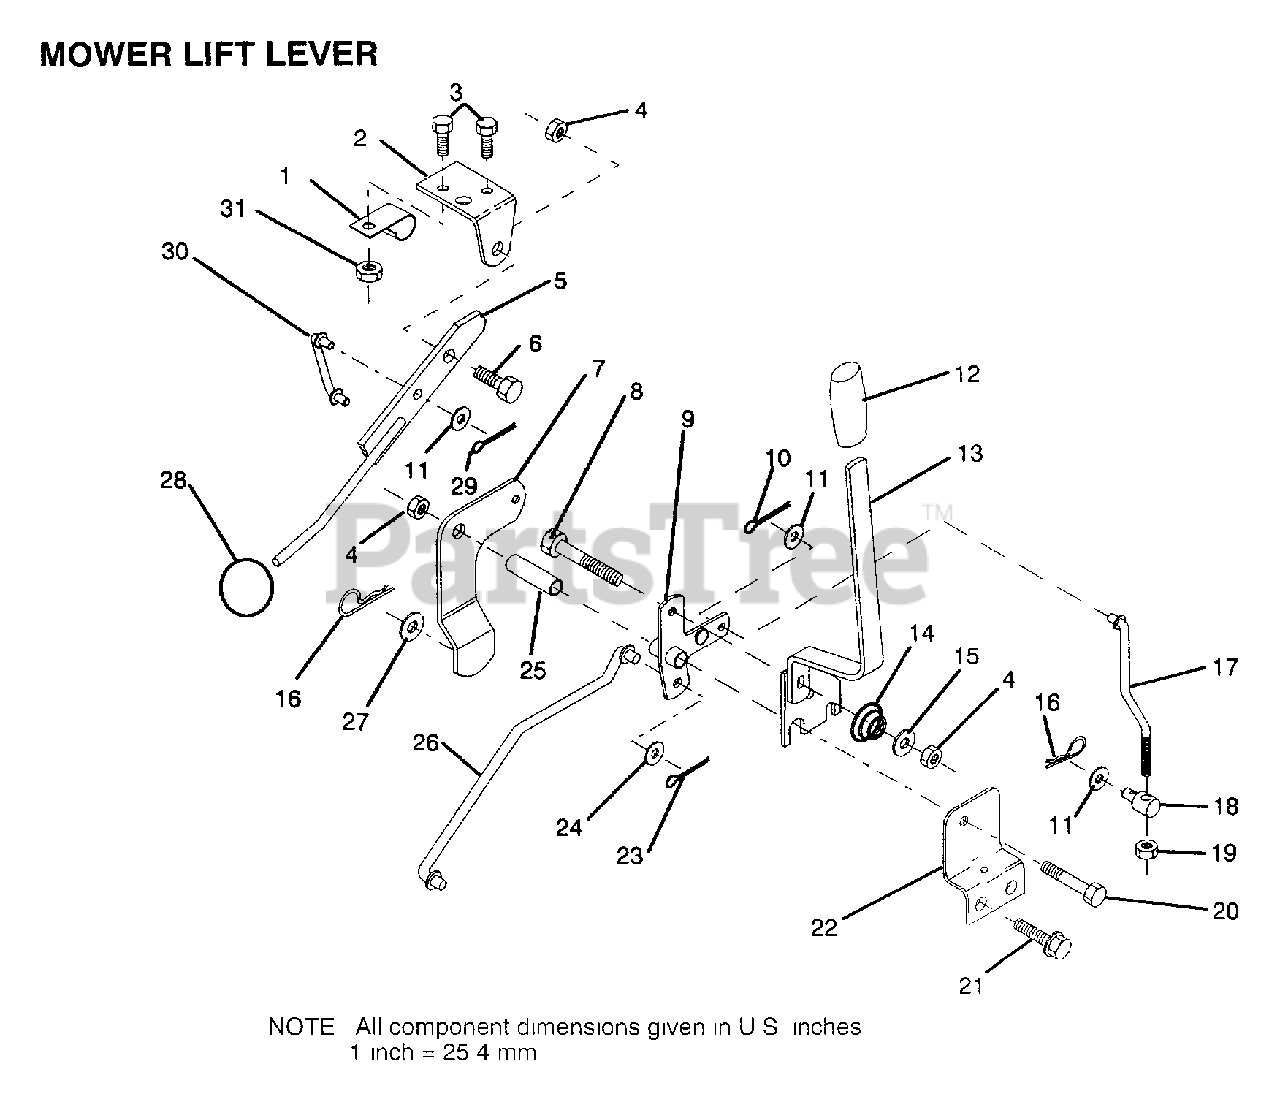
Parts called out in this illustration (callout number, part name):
1	"CLIP,INSULATOR"
2	BRKT CLUTCH
3	BOLT
5	CLUTCH LEVER AS
6	"BOLT, SHOULDER LT"
7	CLUTCH ARM ASS'Y
8	BOLT
9	"BELLCRANK,LIFT"
10	COTTER PIN
11	WASHER
12	GRIP HANDLE
13	"HDLE,LIFT T"
14	SPRING COMPRESSIO
15	WASHER T
16	SPRING.RETAINER
17	LINK FRT LIFT
19	NUT
20	BOLT
21	SCREW LT
22	"BRKT,MOWER HGT"
23	PIN COTTER 1/8
25	TUBE SPACER
26	"ROD,MOWER LIFT "
27	WASHER
28	KNOB T(3/8 HOLE)
30	"LINK,MOWER LIFT"
